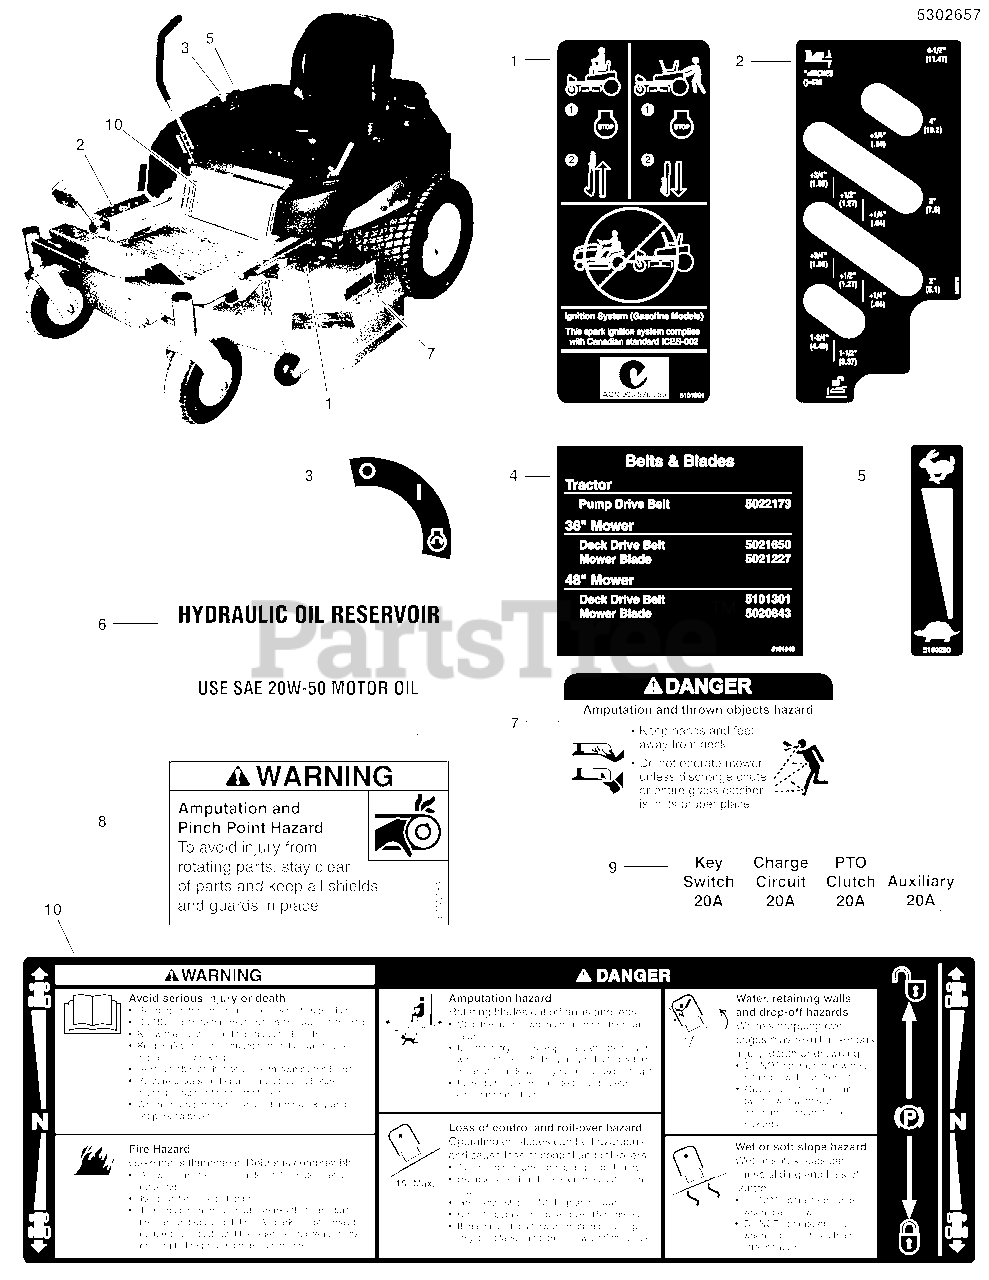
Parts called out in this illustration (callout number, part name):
1	DECAL, TRANSAXLE RELEASE
2	DECAL, CUT HEIGHT, S50X
3	DECAL, IGNITION SWITCH
4	DECAL, BELT AND BLADE, S50X
5	DECAL, THROTTLE CONTROL
6	DECAL, HYDRAULIC OIL, SAE 20W50
7	DECAL, DANGER DO NOT OPERATE W/O DEFLECT
8	DECAL, WARNING, HAND IN BELT, ENG ONLY
9	DECAL, FUSE LOCATION
10	DECAL, MAIN SAFETY
